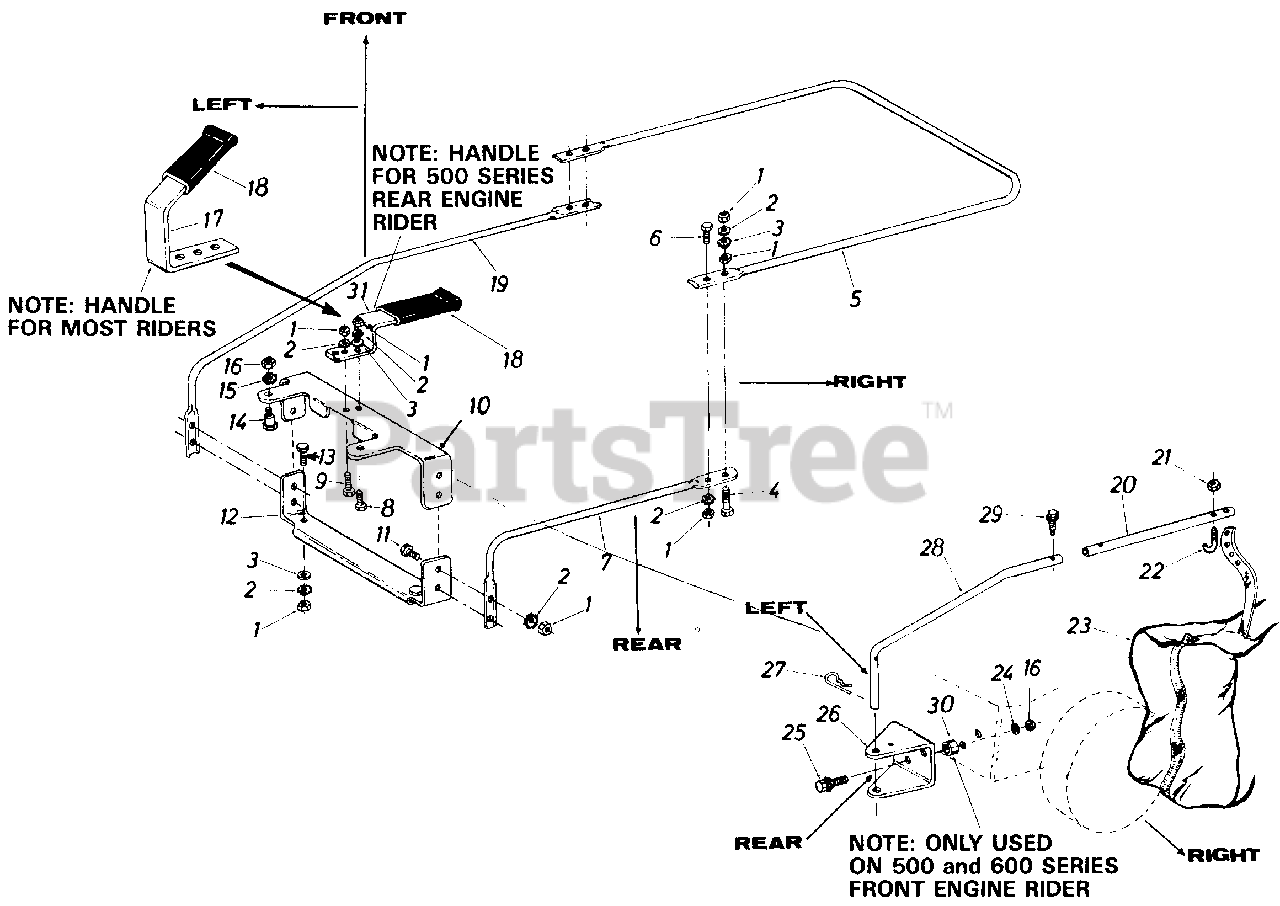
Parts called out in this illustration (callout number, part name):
1	Hex Nut 1/4-20 Thd.*
2	Ext. L-Wash. 1/4" Scr.*
3	Fl-Wash. .281 I.D. x .50 O.D.
4	Hex Scr. 1/4-20 x 1.50" Lg.*
5	Upper Frame Half
6	Hex Scr. 1/420 x 1.00" Lg.*
7	Lower FrameTubing
8	Hex Scr. 1/4-20 x .75" Lg.
9	HexScr. 1/4-20x.75" Lg.*
10	Upper Opening Support
11	Hex Scr. 1/4-20 x 1.0" Lg.*
12	Lower Opening Support
13	Hex Scr. 1/4-20 x .50" Lg.*
14	Shld. Scr. .437 Dia. x .350
15	Ext. L-Wash. 5/16" Scr.*
16	Hex Nut 5/16-18 Thd.*
19	Lower Frame Arm
23	Grass CatcherBag
24	L-Wash. 5/16" I.D.*
25	Hex Sems Scr. 5/16-18 x .75" Lg.*
26	Hitch Bracket
27	Internal Cotter Pin 5/8" Dia.
28	Lower Holding Arm
29	Hex Wash. Hd. Self-Tap .50" Lg.
